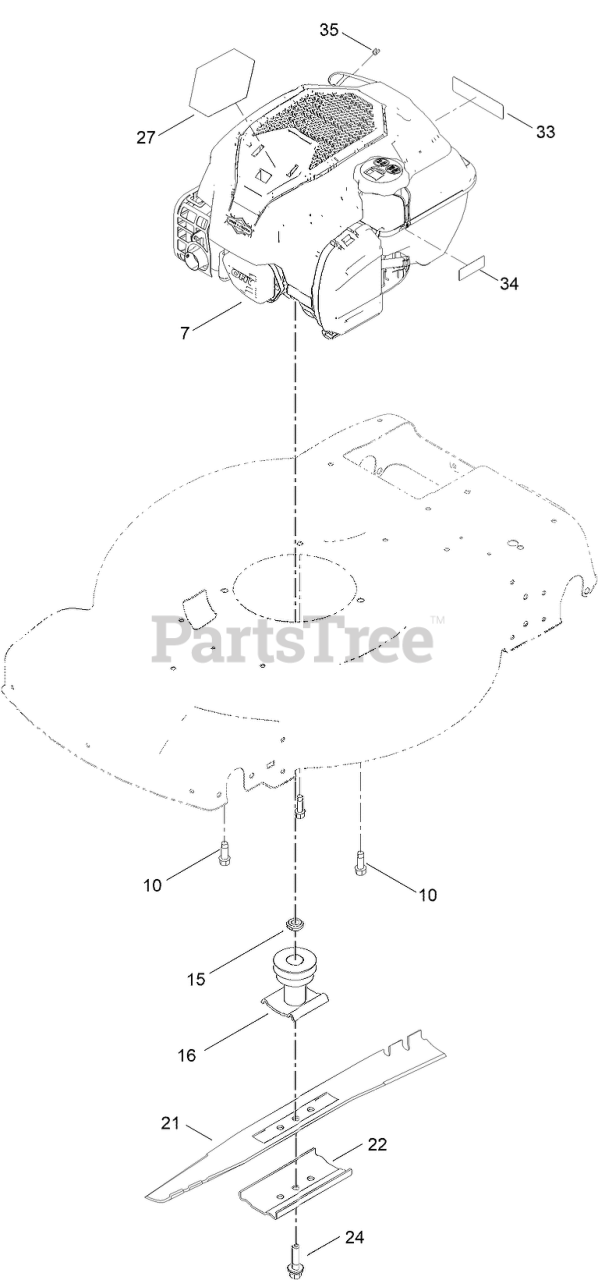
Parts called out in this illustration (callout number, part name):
10	SCREW-THD FORM, HWH
15	SPACER-DRIVER
16	DRIVER-BLADE
22	SUPPORT-BLADE
24	BOLT-BLADE
27	DECAL - BRIGGS 675 EXI SS
33	DECAL-ARRESTOR, SPARK
34	DECAL-LEVEL, FUEL
35	STOP-ROPE
